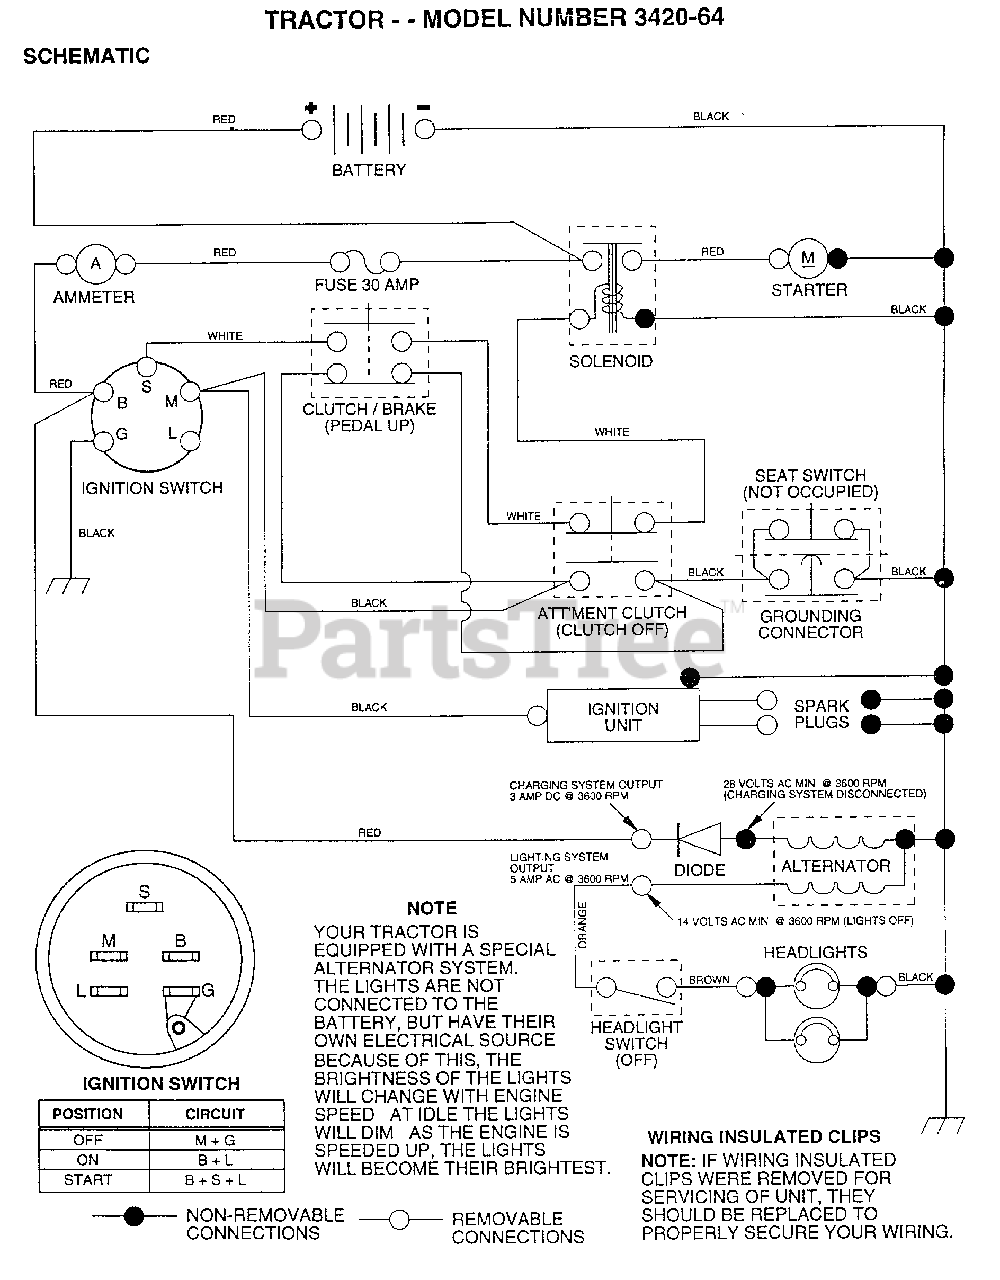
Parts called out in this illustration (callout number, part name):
2	BOLT LT
3	WASHER
4	LOCKWASHER
7	"DRAIN TU T, BATT"
8	"TRAY T, BATTERY"
9	HOSE CLAMP T
16	SWITCH INTERLOCK
20	NUT
21	"HARNESS,LIGHT SOC"
22	HEADLAMP BULB
24	CABLE.6GA.22W/16W
25	"CABLE T, BATTERY"
26	FUSE HYT
28	CABLE.GRND.6GA.21
29	SWITCH SEAT
32	COVER KEY SWITCH
33	KEY MLD GEN DELTA
34	SWITCH LT
36	SCREW
38	BRACKET SWITCH IN
39	SWITCH INTERLOCKT
40	HARNESS.IGN.MECH.
41	BOLT HXHD FIN
44	NUT HXKEP 1/4X20
49	WASHER PINNED
52	PROTECTION LOOP
55	SCREW LT
70	HARNESS ENG DUAL
